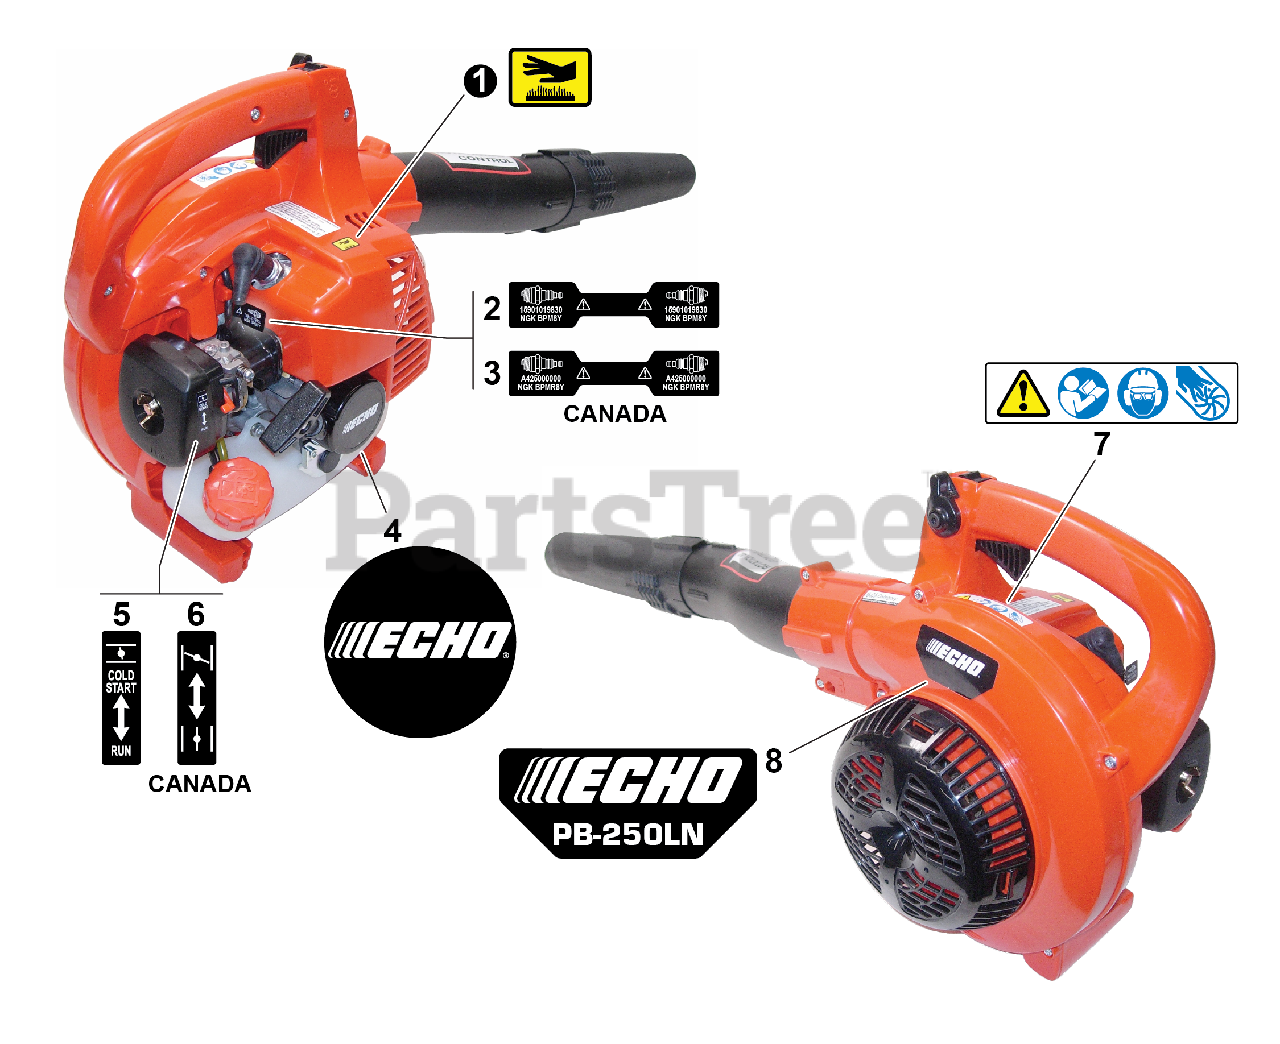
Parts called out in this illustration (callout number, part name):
1	LABEL - HOT SURFACE
2	LABEL - SPARK PLUG -- BPM8Y
3	LABEL - SPARK PLUG -- BPMR8Y
4	LABEL - ECHO
5	LABEL - CHOKE
6	LABEL - CHOKE
7	LABEL - CAUTION
8	LABEL - MODEL -- PB-250LN
